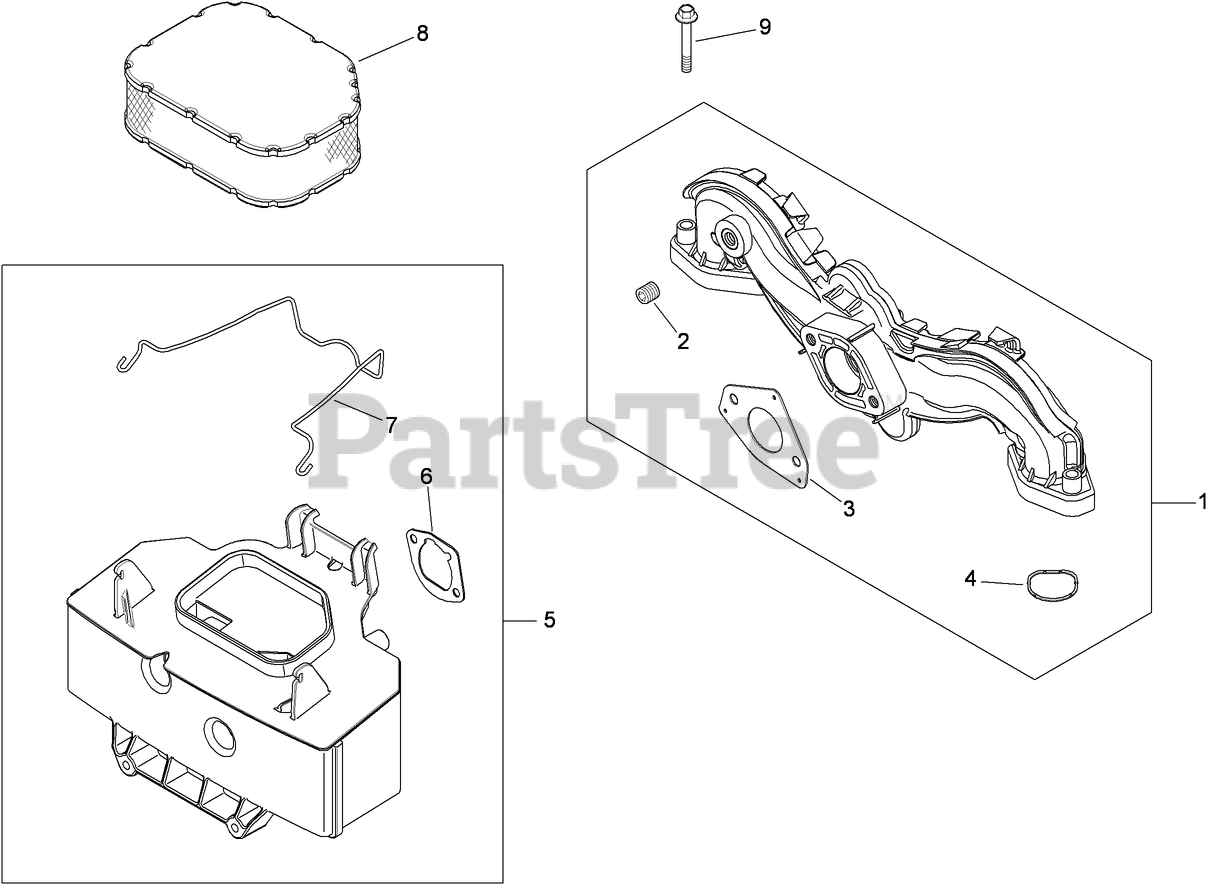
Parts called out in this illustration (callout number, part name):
1	MANIFOLD, INTAKE (INCLUDES 2,3)
2	GASKET-CARBURETOR
3	O-RING
4	PLUG-PIPE, COUNTERSUNK (1/8)
5	AIR CLEANER BASE KIT (INCLUDES 5-6)
6	GASKET-BASE, AIR CLEANER
7	LATCH-ELEMENT, AIR CLEANER
8	ELEMENT-FILTER, AIR
9	SCREW-FLANGE (M6X1.0X40)
